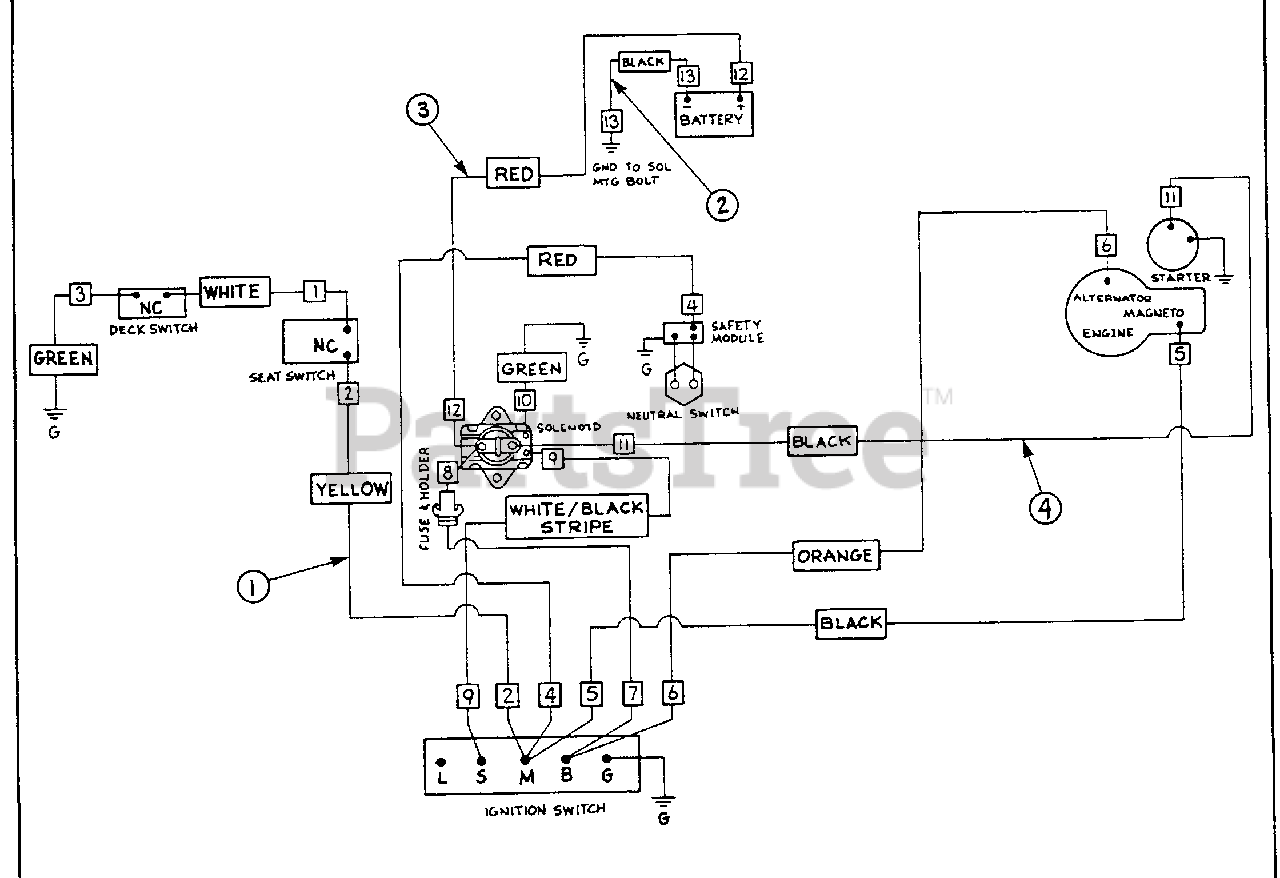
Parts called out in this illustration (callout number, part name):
1	WIRE HARNESS
2	BATTERY CABLE- Ground
3	BATTERY CABLE
4	STARTER CABLE
